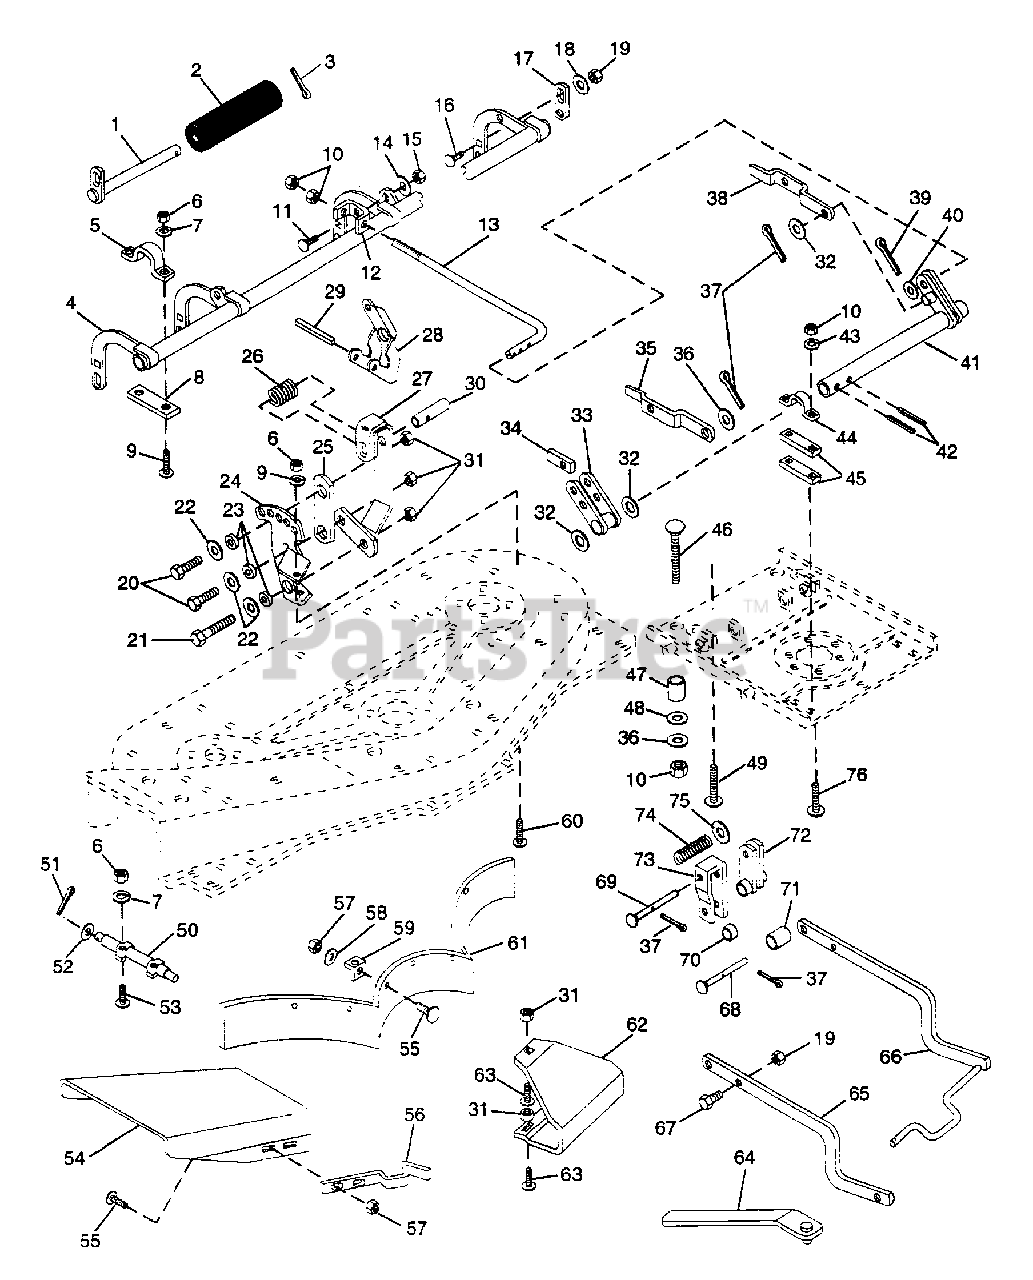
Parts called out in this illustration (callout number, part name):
1	ROLLER SHAFT
3	PIN-COTR .18X1.0 PL
4	ROLLER FRAME 42 INCH
6	NUT-HEX .312-18
7	WSHR-LK .312X.097 PL HVY
8	ADJUSTMENT PLATE
9	BLT-RDHDSQNK .31-18X1.0 SHT PL
10	NUT .50-13 PL
11	BLT-RDHDSQNK .50-13X1.25 PL
13	ADJUSTMENT ROD
14	WSHR-FL-STL .505X.880X.072 PL
15	NUT-LK-CTR .50-13
16	BLT-RDHDSQSHNK .38-16X1.00 PL
18	WSHR-FL-STL .438X1.0X.083 PL
19	NUT-LK-CTR .375-16 GR A PL
20	BLT-HEX .31-18X.75 PL GR2
21	BLT-HEX .31-18X1.25 PL GR5
22	WSHR-FL-STL .328X.875X.062 PL
23	SPACER BUSHING .5 X .32 X .21
24	QUADRANT
26	SG-COMP .045X.50X1.187
27	HANDLE HEIGHT ADJ.
29	PIN-ROLL .188X1.75
31	NUT-LK .312-18 GR A PL
32	WSHR-FL-STL .781X1.250X.059 PL
33	FRONT HANGER LINK
34	WEAR PLATE
35	LEVELING LEVER R.H.
36	WSHR-FL-STL .511X1.441X.125 PL
37	PIN-COTR .12X1.0 PL
38	LEVELING LEVER L.H.
39	PIN-COTR .12X.75 PL
40	WSHR-FL-STL .469X.937X.065 PL
41	FRONT HANGER
42	PIN-ROLL .250X1.25
43	WSHR-LK .500X.151 HVY PL
46	BLT-RDHDSQNK .50-13X2.75 SHTPL
47	SPACER .512X.747X1.567
48	WSHR-FL-STL .505X.880X.072 PL
49	BLT-RDHDSQNK .50-13X1.75 PL
50	HINGE PIN
51	PIN-COTR .09X.75 PL
52	WSHR-FL-STL.406X.812X.065PL
53	BLT-HEX .31-18X.75 PL GR5
54	CHUTE EXTENSION
55	BLT-RDHDSQNK .25-20X.50 SHT PL
56	SPRING, FLAT
57	NUT-LK-CTR .250-20 PL
58	WSHR-FL-STL.281X.62X.065 PL
59	BAFFLE TAB
60	BLT-SERRDHD SL .31-18X.75 YZ
61	BAFFLE-42 IN PAN
62	SKID 42 INCH MOWER
63	BLT-RDHDSQSHNK .31-18X.50 YZ
65	HANGER ARM
66	MOWER HANGER
67	BLT-HEX .38-16X1.00 PL GR5
68	PIN-CLEV .498X4.50 YWZC
69	PIN-CLEV .498X4.31 YWZC
70	SPACER .516X.749X.938
71	SPACER .390X1.000X.562
73	SUPPORT CHANNEL
74	SG-COMP .62X.68X1.75
75	WSHR-FL-STL .531X1.062X.095 PL
76	BLT-RDHDSQNK .50-13X1.50 PL
